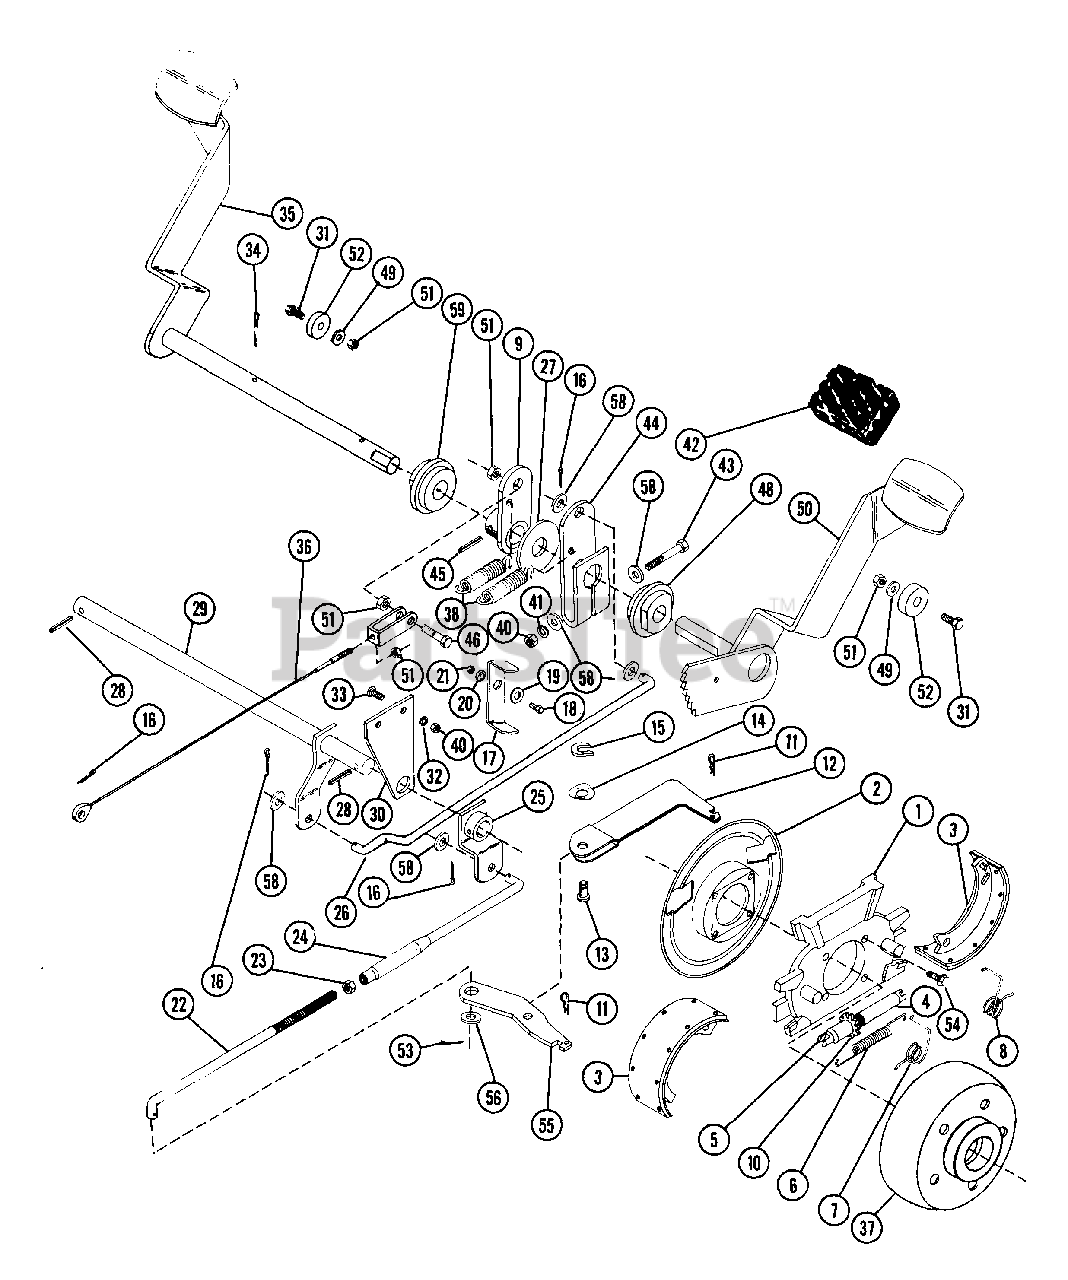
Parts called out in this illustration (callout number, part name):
1	TORQUE SPIDER
2	DUST SHIELD
3	PACKAGE - LINED SHOES
4	PIVOT NUT
5	SOCKET - ADJUSTING SCREW
6	SG-TENS ??X??X?? BENDIX
7	SG-TORS ??X??X?? BENDIX
8	SG-TORS BENDIX 3202132
9	CLUTCH LEVER
10	ADJUSTING SCREW
11	PIN-HAIR EXT .12X.75
12	STRUT ASSEMBLY
13	CLEVIS PIN
14	WSHR-FL-STL .380X.781X.013 PL
15	RETAINER
16	PIN-COTR .12X.75 PL
17	BRAKE LATCH
18	BLT-HEX .25-20X.75 PL GR2
19	WSHR-FL-STL.281X.62X.065 PL
20	SPACER BUSHING .37 X .26 X .14
21	NUT-LK-CTR .250-20 PL
22	LOWER SHIFT ROD
23	NUT-JAM .312-24 PL
24	BRAKE ROD
25	BRAKE ARM
26	BRAKE ROD
27	WSHR-FL-STL .755X1.375X.062 PL
28	PIN-GRV .250X1.25 TP A
29	BRAKE SHAFT
31	BLT-HEX .31-18X1.00 PL GR 2
32	WSHR-LK .375X.115 HVY PL
33	BLT-RDHDSQSHNK .38-16X1.00 PL
34	PIN-COTR .18X1.25 PL
35	L H LEVER
35	L.H. LEVER
36	CLUTCH CABLE
37	BRAKE DRUM
38	SG-TENS .090X.75X3.50 WLD 34
40	NUT-HEX .375-16
41	WSHR-LK .375X.094 MED PL
42	PEDAL PAD
43	BLT-HEX .38-16X2.25 GR2
44	ARM-BRAKE
45	PIN-ROLL .188X1.25
46	BLT-HEX .31-18X.75 PL GR5
48	BSHG-FLG .750X1.750X.875X2.125
49	WSHR-FL-STL .38X.875X.083 PL
50	R.H. LEVER
51	NUT-LK .312-18 GR A PL
52	SPACER .344X1.000X.375
53	PIN-COTR .09X.75 PL
54	SCR-TAP .250-20X.50 HH F
55	PARKING BRAKE LEVER
56	WSHR-FL-STL .323X.625X.062 PL
58	WSHR-FL-STL.406X.812X.065PL
59	BSHG-FLG .750X1.750X.875X2.125
59	BSHG-FLG 1.375X1.75X.875X2.125
